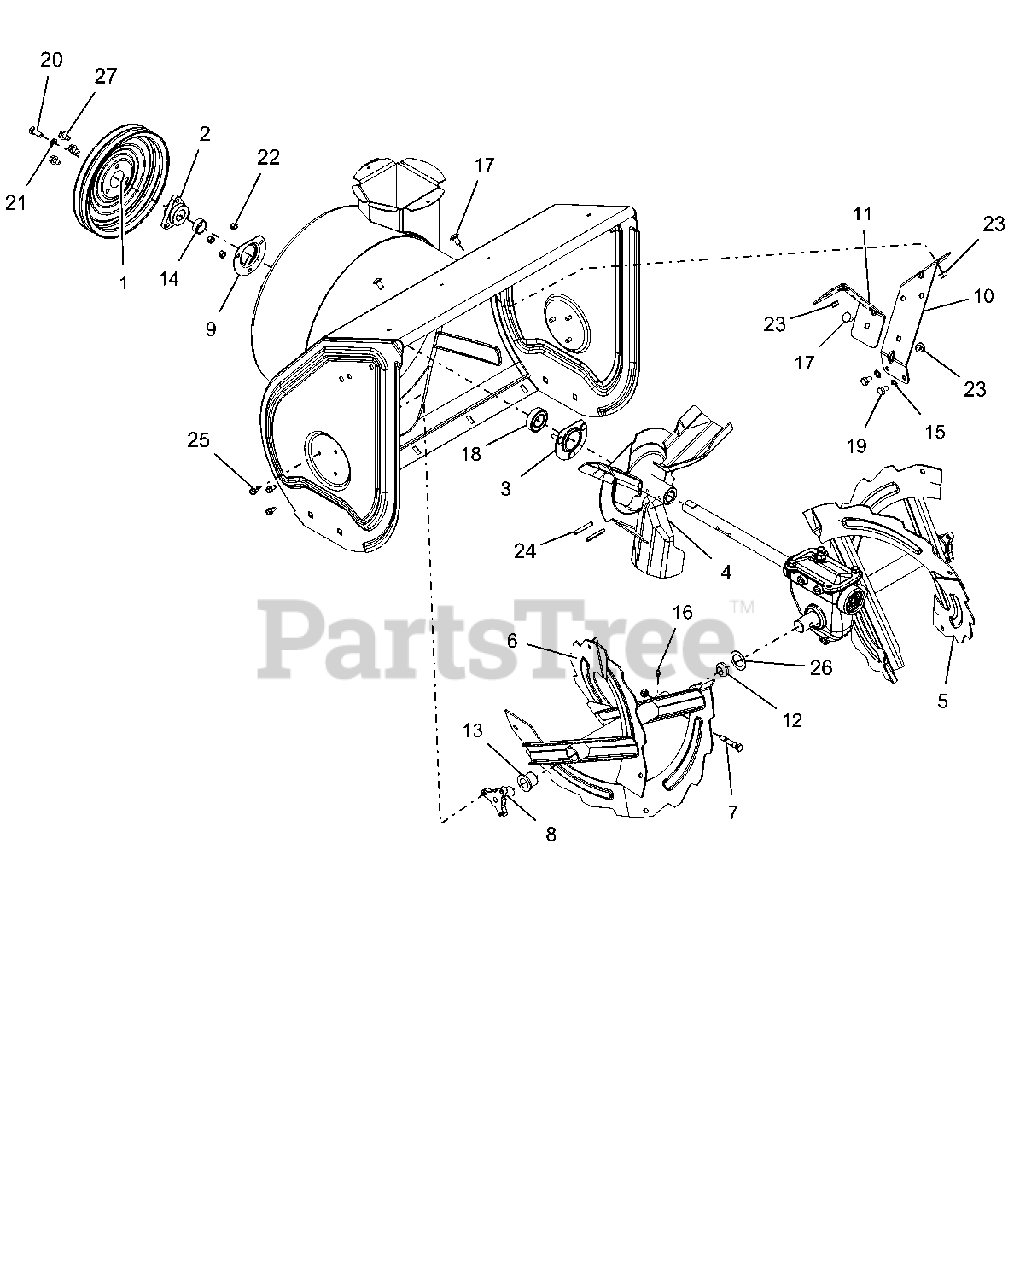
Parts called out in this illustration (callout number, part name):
1	PULLEY, SPIN FORM DUAL GROOVE
2	PULLEY HUB, D-BORE .87 DELUXE
3	BEARING FLANGE
4	IMPELLER, 3 BLADE-14"
5	RAKE, LH W/ZERK - 24"
6	RAKE, RH W/ZERK - 24"
7	SHEAR BOLT SERVICE ASSEMBLY
8	SUPPORT, RAKE BUSHING
9	BEARING FLANGE
10	BRACKET, GEARCASE SUPPORT - LH
11	BRACKET, GEARCASE SUPPORT - RH
12	PLUG, RAKE TUBE
13	BSHG-FLG, NY.778 ID X 1.018 OD
14	BSHG-SPCR .895IDX1.065ODX.353
15	@WSHR-LK-EXT.326X.599X.031YWZC
16	ZERK,FITTING .25X.125 DRIVE IN
17	BLT-RDHDSQSHNK.31-18X.62 YZ-LK
18	BRG-BALL .876 X 1.750 X .50
19	@BLT-HEX .31-18X.50 GR5 YWZC
20	BLT-HEX .31-24X.75 YWZC GR5
21	WSHR-LK .312X.097 HVY YWZC
22	@NUT-LK-CTR .25-20 YWZC
23	@NUT-LK-TOP-FLG .31-18 YWZC
24	PIN-ROLL .250X1.75
25	SCR-TAP .25-20X.50 HWH TR YWZ
26	WSHR-FL-STL 1.010X1.505X.062YZ
27	@SCR-TAP .31-18X.50 HWH TR YWZ
